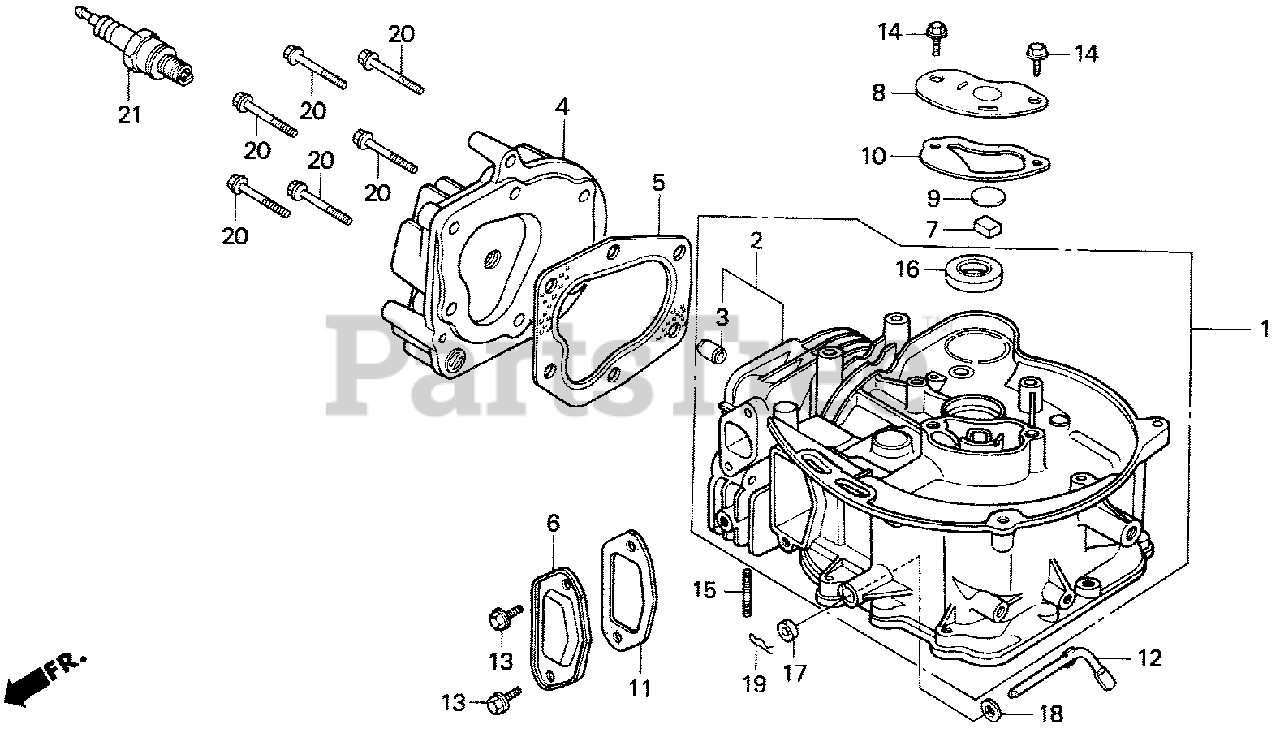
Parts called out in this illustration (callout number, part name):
1	CYLINDER ASSY.
2	CYLINDER
3	GUIDE, VALVE (OVER SIZE)
3	GUIDE, VALVE (OVER SIZE) Use up to Engine SN 2504133.
4	CYLINDER HEAD
5	GASKET, CYLINDER HEAD
6	COVER, TAPPET ROOM
7	FILTER, BREATHER
8	CAP, BREATHER CHAMBER
9	VALVE, BREATHER
10	GASKET, BREATHER CAP
11	GASKET, TAPPET COVER
12	SHAFT, GOVERNOR ARM
13	BOLT, FLANGE (5X10)
14	BOLT, FLANGE (6X12) (CT200)
15	BOLT, STUD (6X50)
16	OIL SEAL (17X30X6) (NOK)
17	OIL SEAL (5X10X4)
18	WASHER, PLAIN (5MM)
19	PIN, LOCK (8MM)
20	BOLT, FLANGE (6X35)
21	SPARK PLUG (BMR4A) (NGK)
21	SPARK PLUG (W14MR-U) (DENSO)
